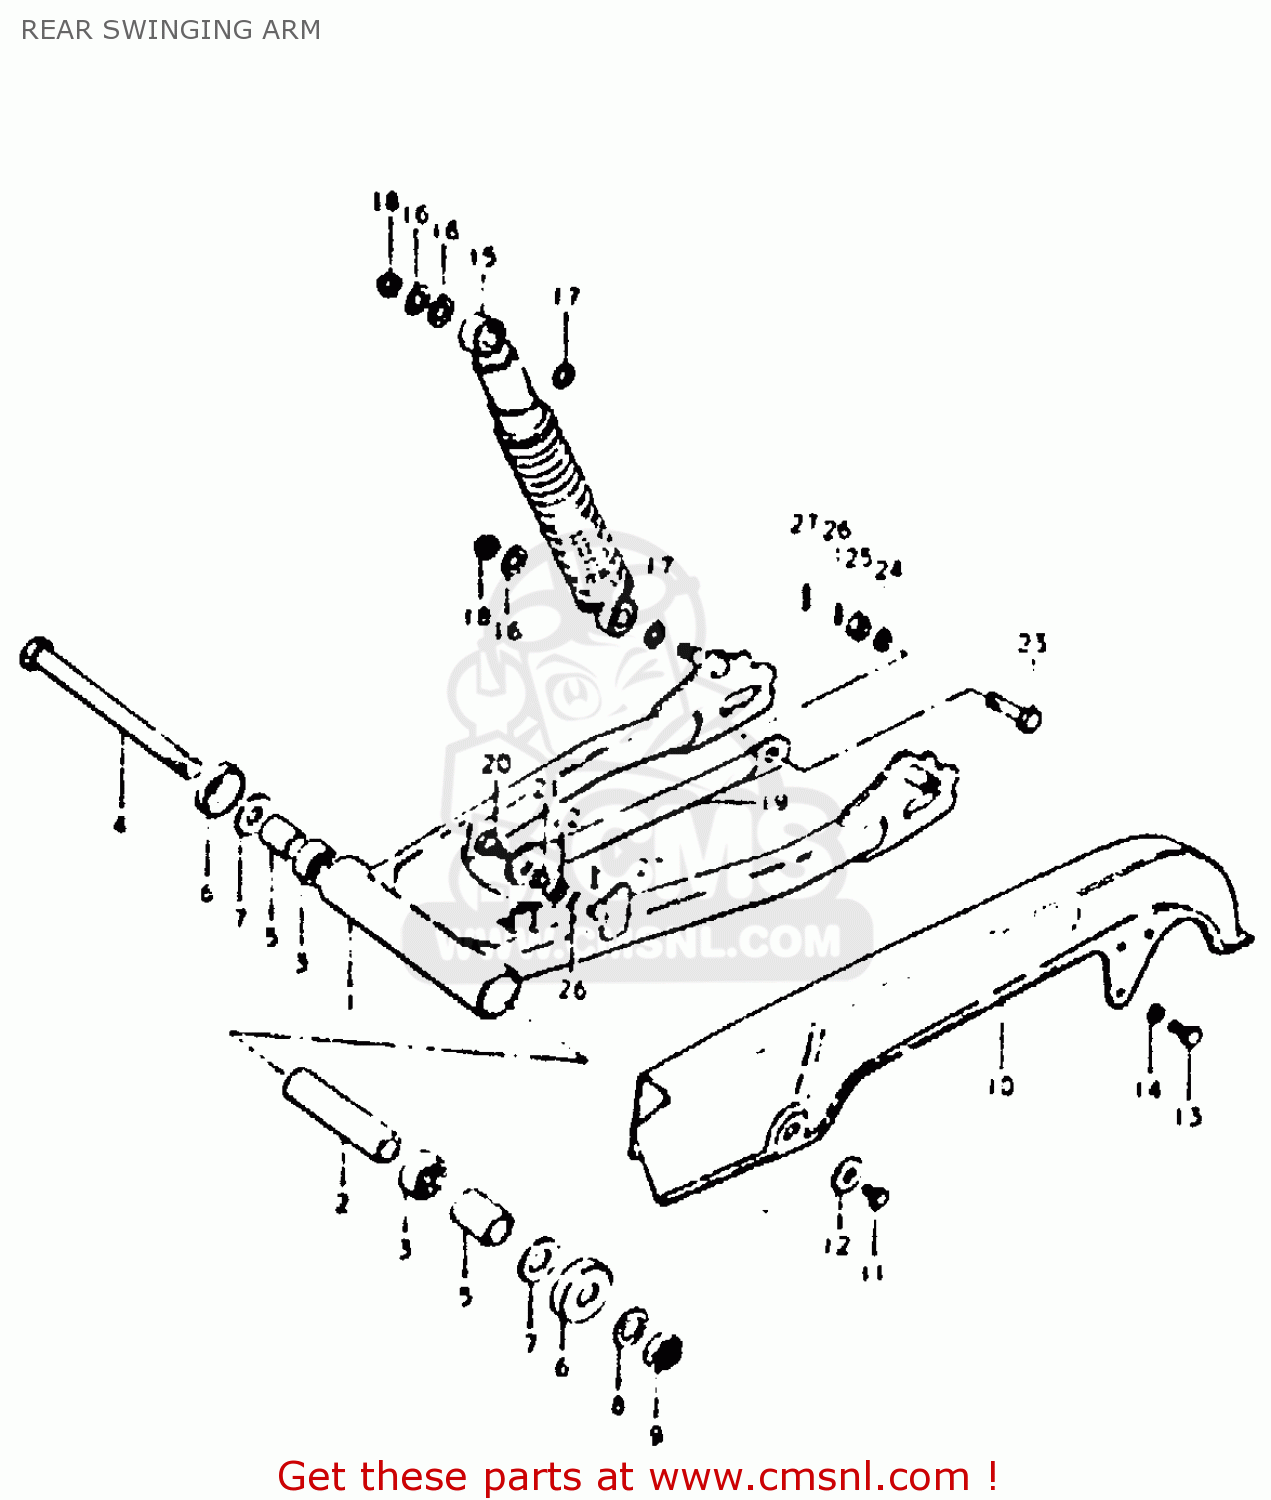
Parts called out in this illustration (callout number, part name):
1	REAR SWINGING ARM SET
2	SPACER, CENTER
3	BEARING(22X29X30)
4	SHAFT,REAR SWING ARM
5	SPACER,RR SWGARM PIVOT
6	CVR,RR SWGARM DUST SEAL(OD:40)
7	WASHER(14.2X34X1)
8	WASHER
9	NUT 14MM
10	CASE,CHAIN
11	BOLT
12	WASHER
13	BOLT, UPPER
14	LOCK WASHER
15	SHOCK ABSORBER, REAR
16	WASHER
17	WASHER
18	NUT, LOWER LH
19	TORQUE LINK, REAR
20	BOLT(8X22.5)
21	LOCK WASHER
22	NUT
23	BOLT(10X31)
24	LOCK WASHER
25	NUT
26	CLIP
27	PIN
